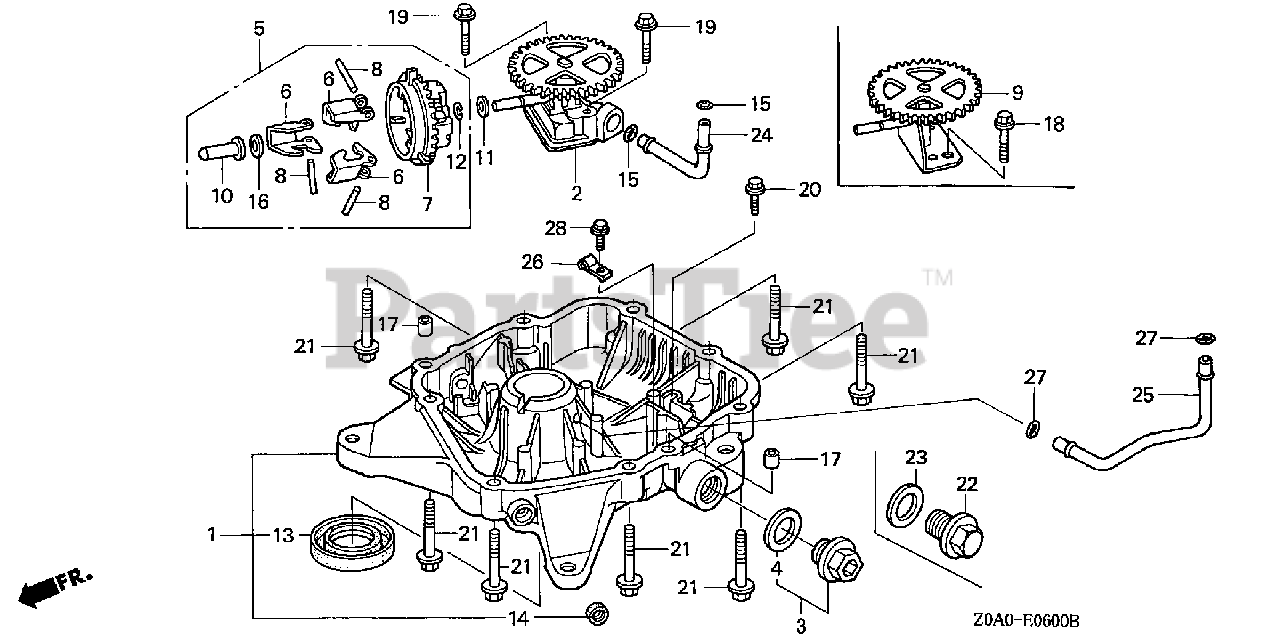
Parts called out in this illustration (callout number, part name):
1	PAN ASSY., OIL
2	PUMP ASSY., OIL
5	GOVERNOR ASSY.
6	WEIGHT, GOVERNOR
7	HOLDER, GOVERNOR WEIGHT
8	PIN, GOVERNOR WEIGHT
10	SLIDER, GOVERNOR
11	WASHER (6X16)
12	CLIP, GOVERNOR HOLDER
13	OIL SEAL (31X50X8)
14	OIL SEAL (10X16X4.5)
15	O-RING (7.5X2.3)
16	WASHER, PLAIN (6MM)
17	PIN A, DOWEL (8X14)
19	BOLT, FLANGE (6X30)
21	BOLT, FLANGE (8X40)
22	BOLT, DRAIN PLUG (20MM)
23	WASHER, DRAIN PLUG (20MM)
24	PIPE, OIL PUMP
25	PIPE, OIL SUPPLY
26	HOLDER, OIL PIPE
27	O-RING (5.8X2)
28	BOLT, FLANGE (6X12)
